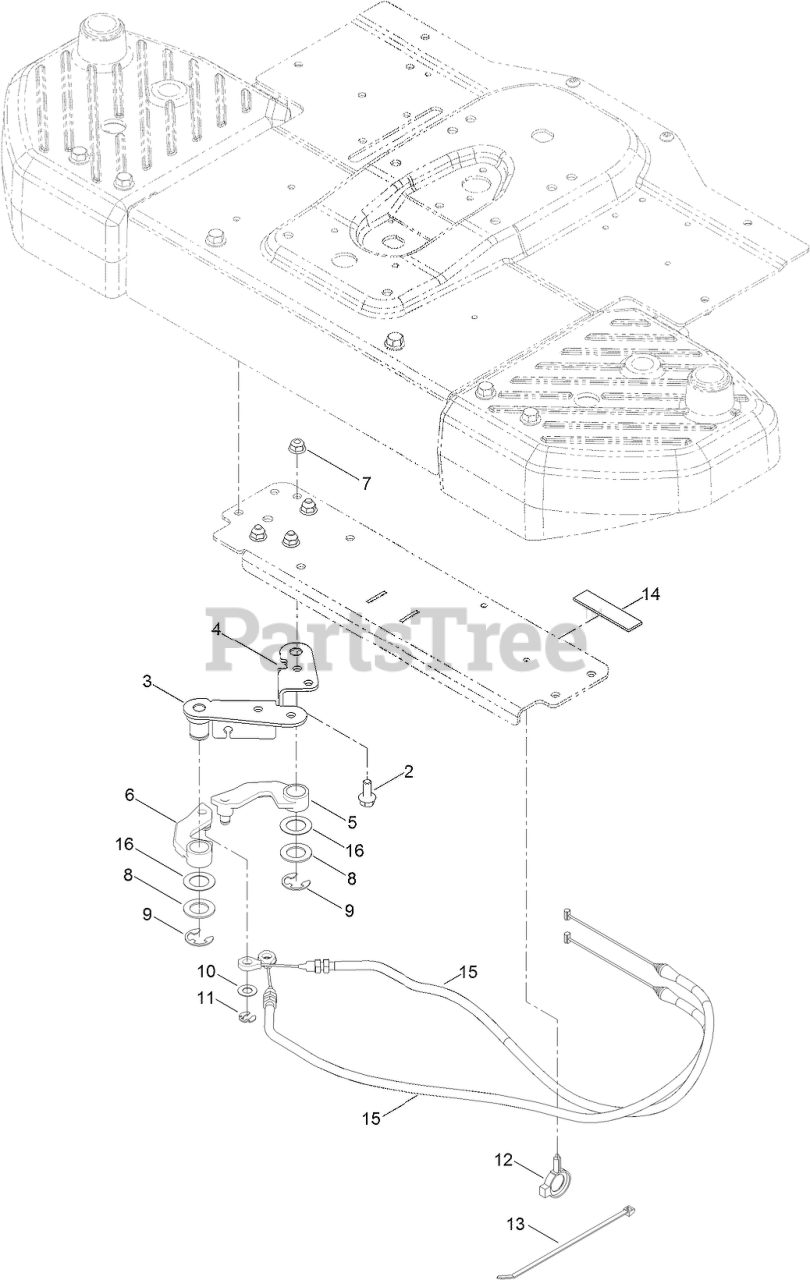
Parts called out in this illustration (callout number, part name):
2	SCREW-HHF
3	CABLE BRACKET ASM
4	CABLE BRACKET ASM
5	ARM-CABLE, RH
6	ARM-CABLE, LH
7	NUT-HF, NI
8	WASHER-THRUST
9	E-RING
10	WASHER-THRUST
11	RING-RETAINING
12	CLAMP-HOSE
13	TIE-CABLE
14	STRIP-SEAL
15	CABLE-STEERING
16	WASHER-THRUST
